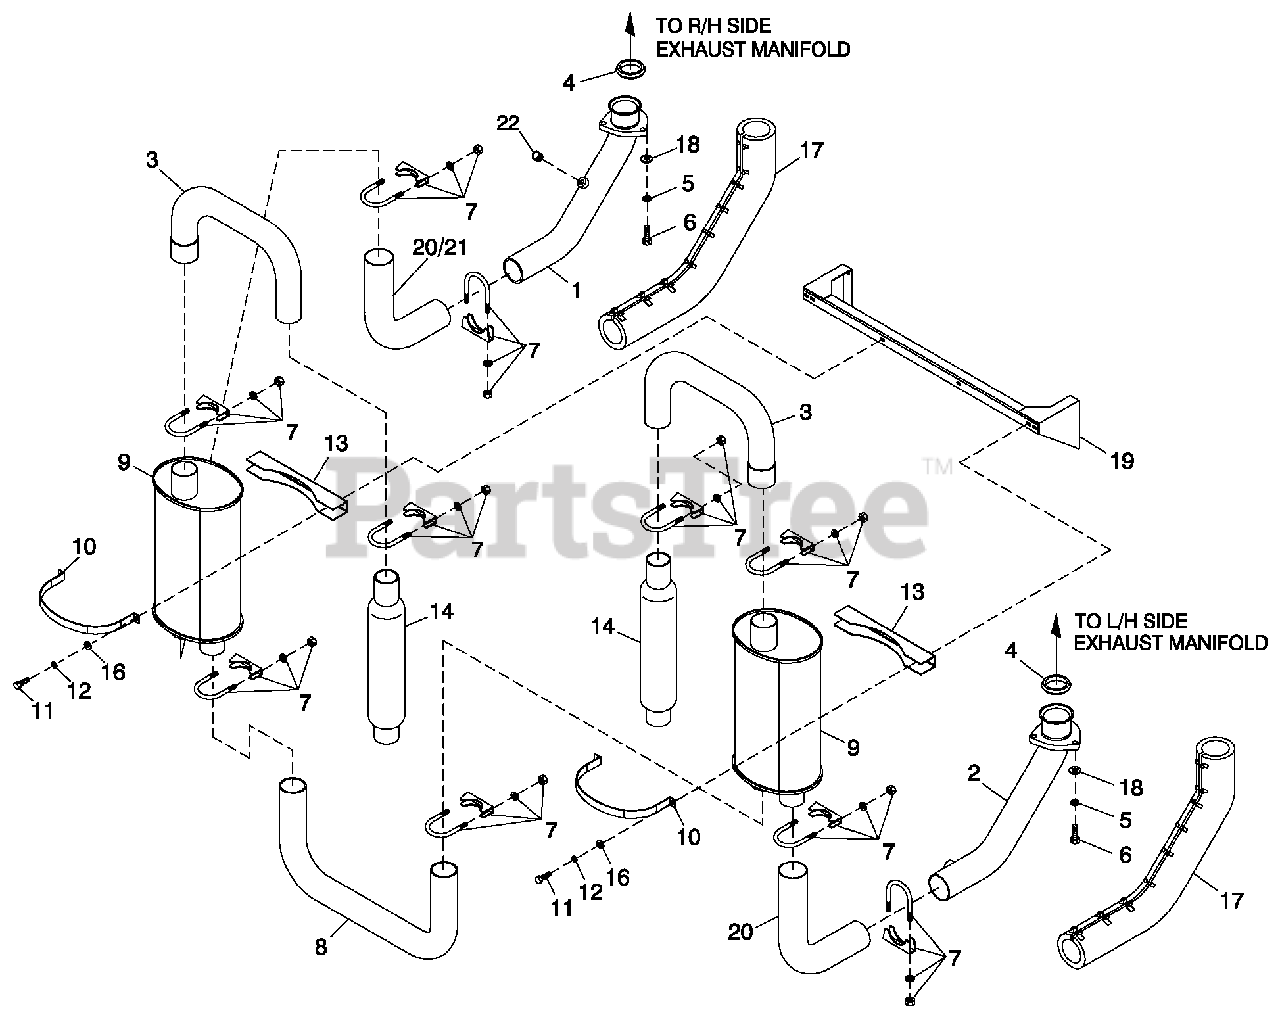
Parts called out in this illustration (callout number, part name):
1	PIPE EXH MANIFOLD 6.8L C3 RH (6.8L 70KW)
2	PIPE EXH MANIFOLD 6.8L C3 LH (6.8L 70KW)
3	PIPE EXHAUST MUFFLER OUT
4	RING GASKET, 2.5DIA
5	WAS HER LOCK M10SS
6	SCREW HHC M10-1.5 X 50 S S FTH
7	BOLT U 3/8-16X2.62
8	PIPE EXHAUST CROSSOVER
9	MFLR 7" X 9" X 25" (2) 2.5" IN/2.5" OUT
10	MUFFLER STRAP
11	SCREW HHC M6-1.0X 16 G8.8
12	WAS HER LOCK M6-1/4
13	MUFFLER BRACKET STIFFENER
14	GLAS S PACK 23.5" LG 2.5" IN/OUT
16	WAS HER FLAT 1/4-M6 ZINC
17	EXHAUS T BLANKET 800MM LG (6.8L 70KW)
18	WAS HER FLAT 3/8 S S
19	BRKT MUFFLER
20	PIPE LH MUFFLERS IDE
21	PIPE RH MUFFLER SIDE
22	PLUG M18-1.50
